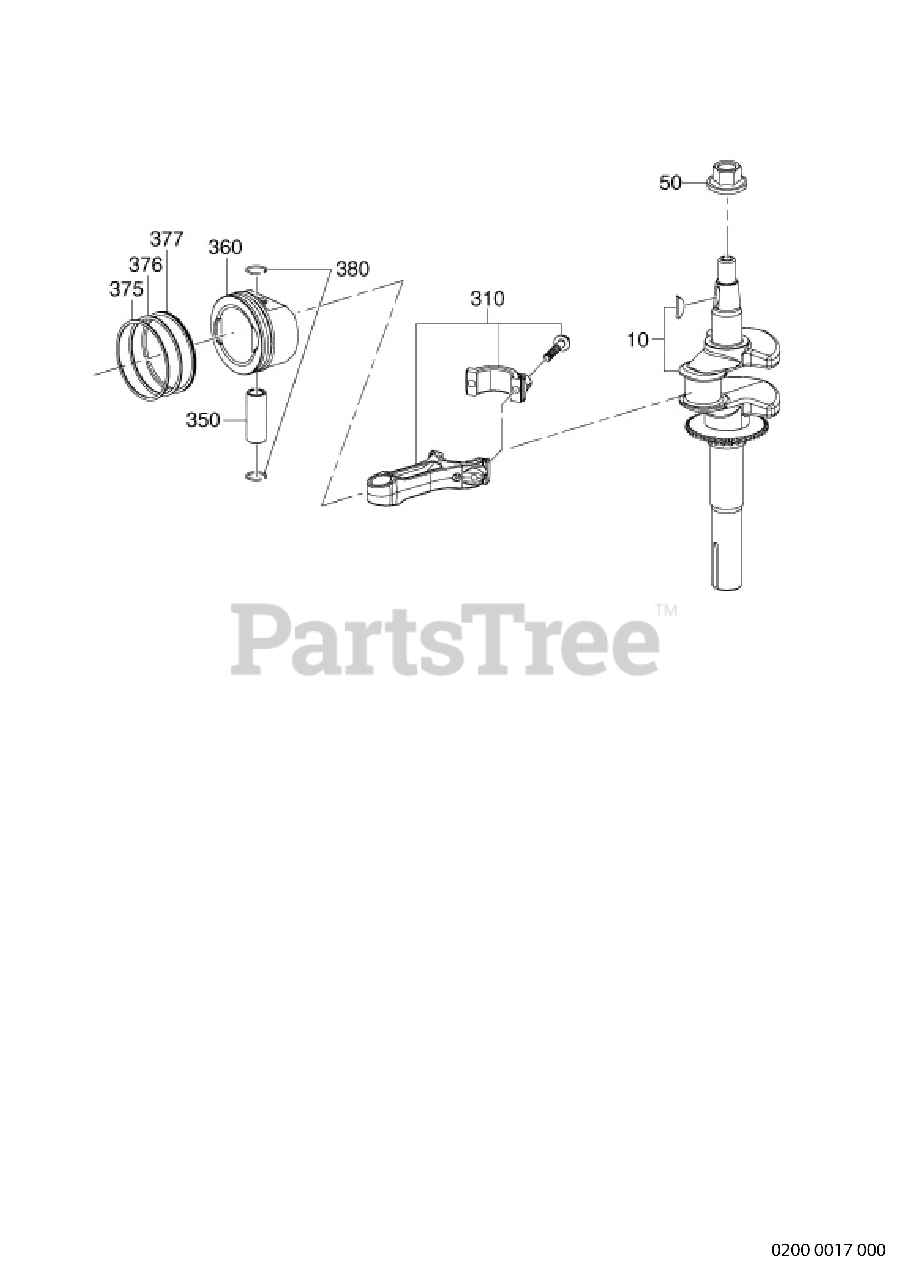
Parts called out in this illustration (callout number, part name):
10	CRANKSHAFT ASSY
310	CONNECTING ROD ASSY
360	PISTON
375	FIRST PISTON RING
376	SECOND PISTON RING
380	PISTON PIN SNAP RING
